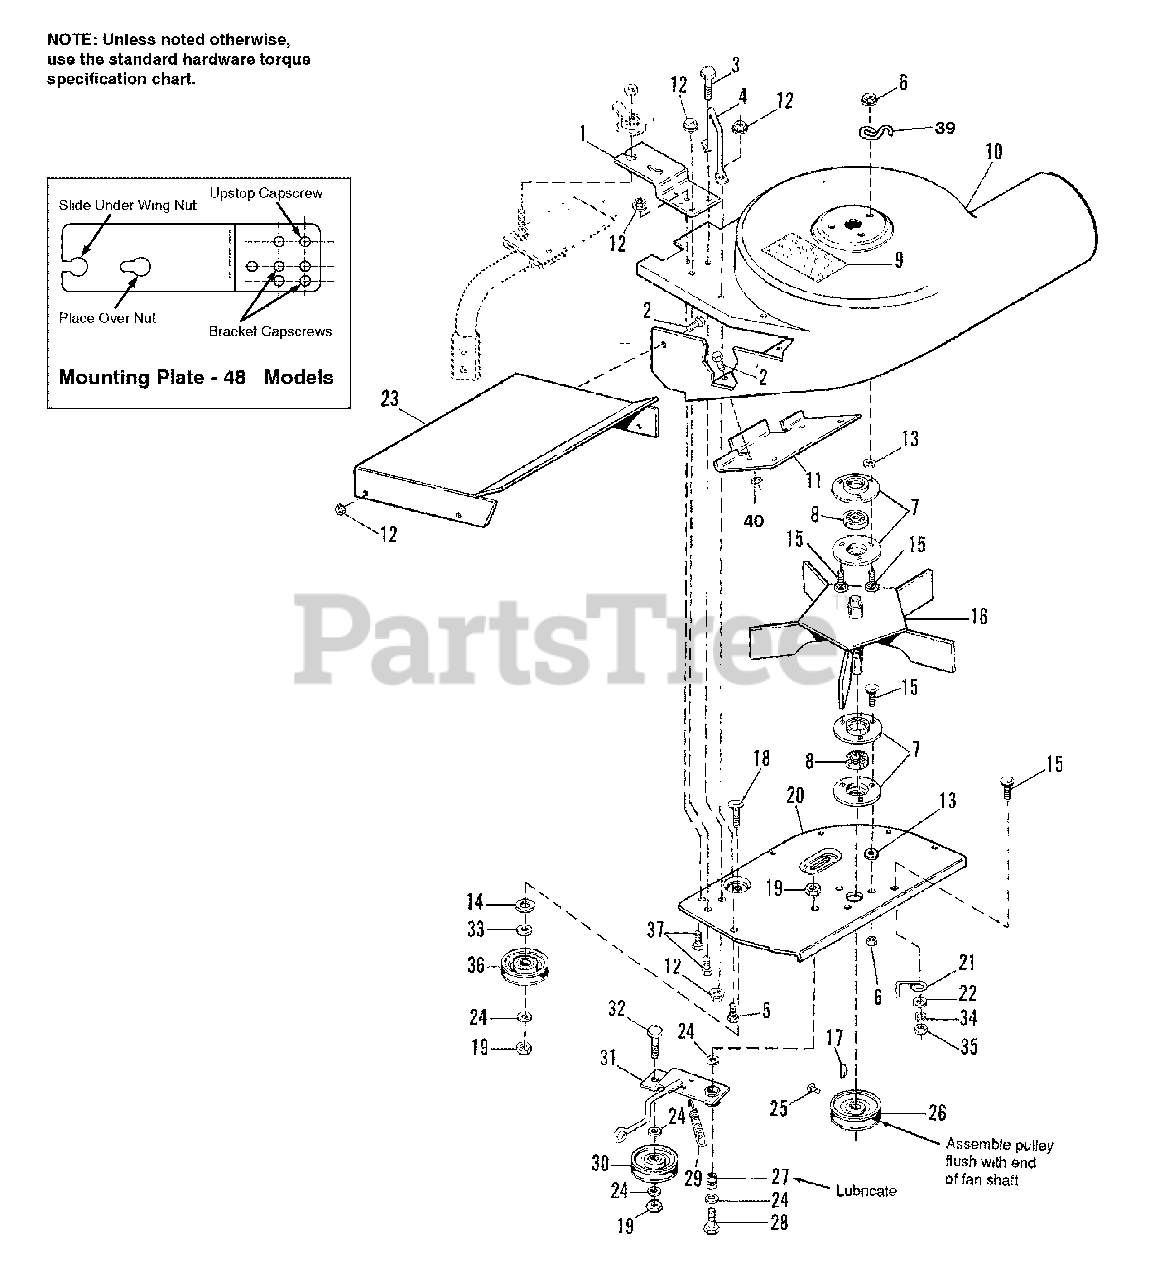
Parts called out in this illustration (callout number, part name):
1	PLATE, Mounting
2	CAPSCREW, Hex Head,1/4-20 x 5/8
3	CAPSCREW, Hex Head,1/4-20 x 2-1/4
4	STOP, Deflector
5	CAPSCREW, Hex Head, 1/4-20 x 7/8
6	NUT, Hex Flange Whiz Lock, 5/16-18
7	RETAINER, Bearing
8	BEARING
9	DECAL, Danger
10	HOUSING, Blower
11	HOOK, Stone Guard
12	NUT, Hex Flange Whiz Lock, 1/4-20
13	NUT, Push, 5/16
14	WASHER, Plain, 1/2
15	BOLT, Carriage, 5/16-18 x 3/4
16	FAN ASSEMBLY, 5 Blade
17	KEY, Woodruff, 3/16
18	BOLT, Carriage, 3/8-16 x 1-1/4
19	NUT, Hex Jam Lock, 3/8-16
20	PLATE, Shroud
21	STOP, Belt
22	WASHER, 5/16
23	COVER, Top
24	WASHER, 3/8
25	SETSCREW, 5/16-18 x 3/8
26	PULLEY, Driven
27	SPACER
28	CAPSCREW, Hex Head, 3/8-16 x 1-1/2
29	SPRING, Extension
30	PULLEY, Idler, Adjustable
31	IDLER ARM ASSEMBLY
32	CAPSCREW, Hex Head, 3/8-16 x 1
33	WASHER, Special, 3/8 x 1 OD
34	WASHER, Lock, 5/16
35	NUT, Hex, 5/16-18
36	PULLEY, Idler, Fixed
37	CAPSCREW, Hex Head, 1/4-20 x 3/4
39	S-HOOK
40	NUT, Ny-Lock, 1/4-20
